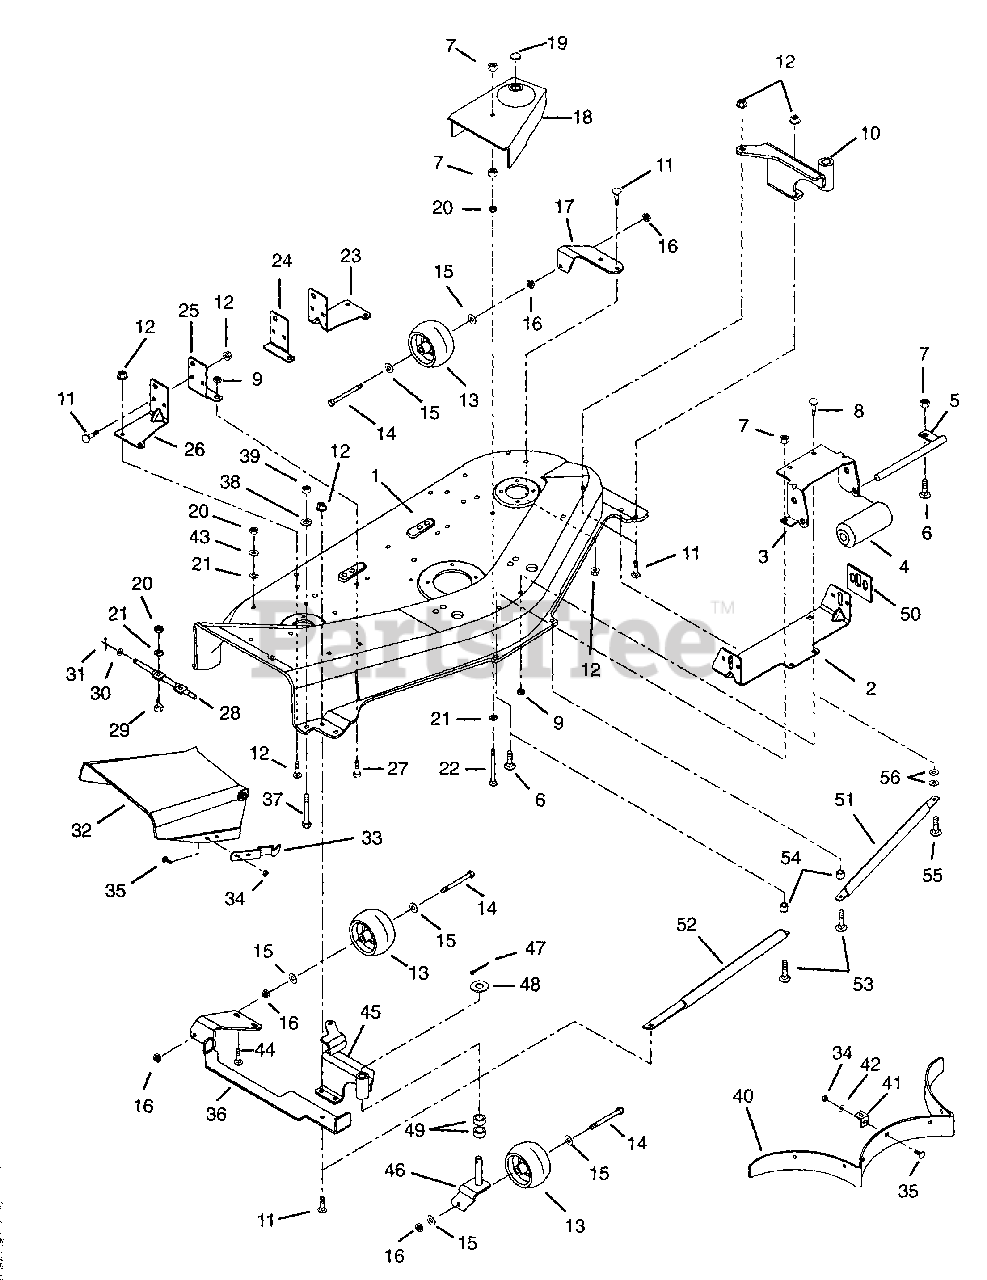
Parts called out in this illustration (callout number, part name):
1	MOWER PAN W/DECALS 48"- ORANGE
2	FRONT HANGER
3	BRACKET, ROLLER
5	ROLLER SHAFT
6	BLT-RDHDSQNK .31-18X.75 GR5 PL
7	NUT-LK .312-18 GR A PL
8	BLT-RDHDSQNK .50-13X.75 SHT PL
9	NUT-LK-NYL .50-13 GR 5 PL
10	WELDMENT-LEFT FRONT
11	BLT-RDHDSQNK.31-18X.75GR5SHTPL
12	NUT-FLG. .312-18 PL
14	BLT-HEX .38-16X3.50 PL GR5
15	WSHR-FL-STL .38X.875X.083 PL
16	NUT-LK-CTR .375-16 GR A PL
17	BRACKET-LEFT REAR
18	BELT COVER R H 48"
18	BELT COVER L H 48"
19	BUTTON PLUG 1.0
20	NUT-HEX .312-18
21	WSHR-LK .312X.097 PL HVY
22	BLT-RDHDSQNK .31-18X3.25 SHTPL
23	LH REAR HANGER
24	LH REAR HANGER SUPPORT
25	RH REAR HANGER SUPPORT
26	RH REAR HANGER
27	BLT-HEX .50-13X1 PL GR5
28	HINGE PIN
29	BLT-HEX .31-18X.75 PL GR5
30	WSHR-FL-STL.406X.812X.065PL
31	PIN-COTR .09X.75 PL
32	CHUTE EXTENSION
33	SPRING, FLAT
34	NUT-LK-CTR .250-20 PL
35	BLT-RDHDSQNK .25-20X.50 SHT PL
36	WELDMENT-RIGHT REAR
37	BLT-HEX.38-16X2.5FTHD GR2 YWZC
38	WSHR-LK .375X.115 HVY PL
39	NUT-HEX .375-16
40	BAFFLE
41	BAFFLE TAB
42	WSHR-FL-STL.281X.62X.065 PL
43	WSHR-FL-STL.312X.734X.065PL
44	BLT-RDHDSQNK .31-18X1.00 PL
45	WELDMENT-RIGHT FRONT
46	CASTER FORK, WELDMENT
47	PIN-COTR .18X1.25 PL
48	WSHR-FL-STL .630X1.005X.062 PL
49	BSHG-SLV .625X.750X.500 BR
50	MOWER ADJUSTMENT TAB
51	GUARD - FOOT - LH
52	GUARD - FOOT - RH
53	BLT-RDHDSQNK .31-18X1.50 PL
54	SPACER .375 X .625 X .500
55	BLT-RDHDSQNK .31-18X1.25
56	WSHR-FL-STL .390X.750X.125 PL
